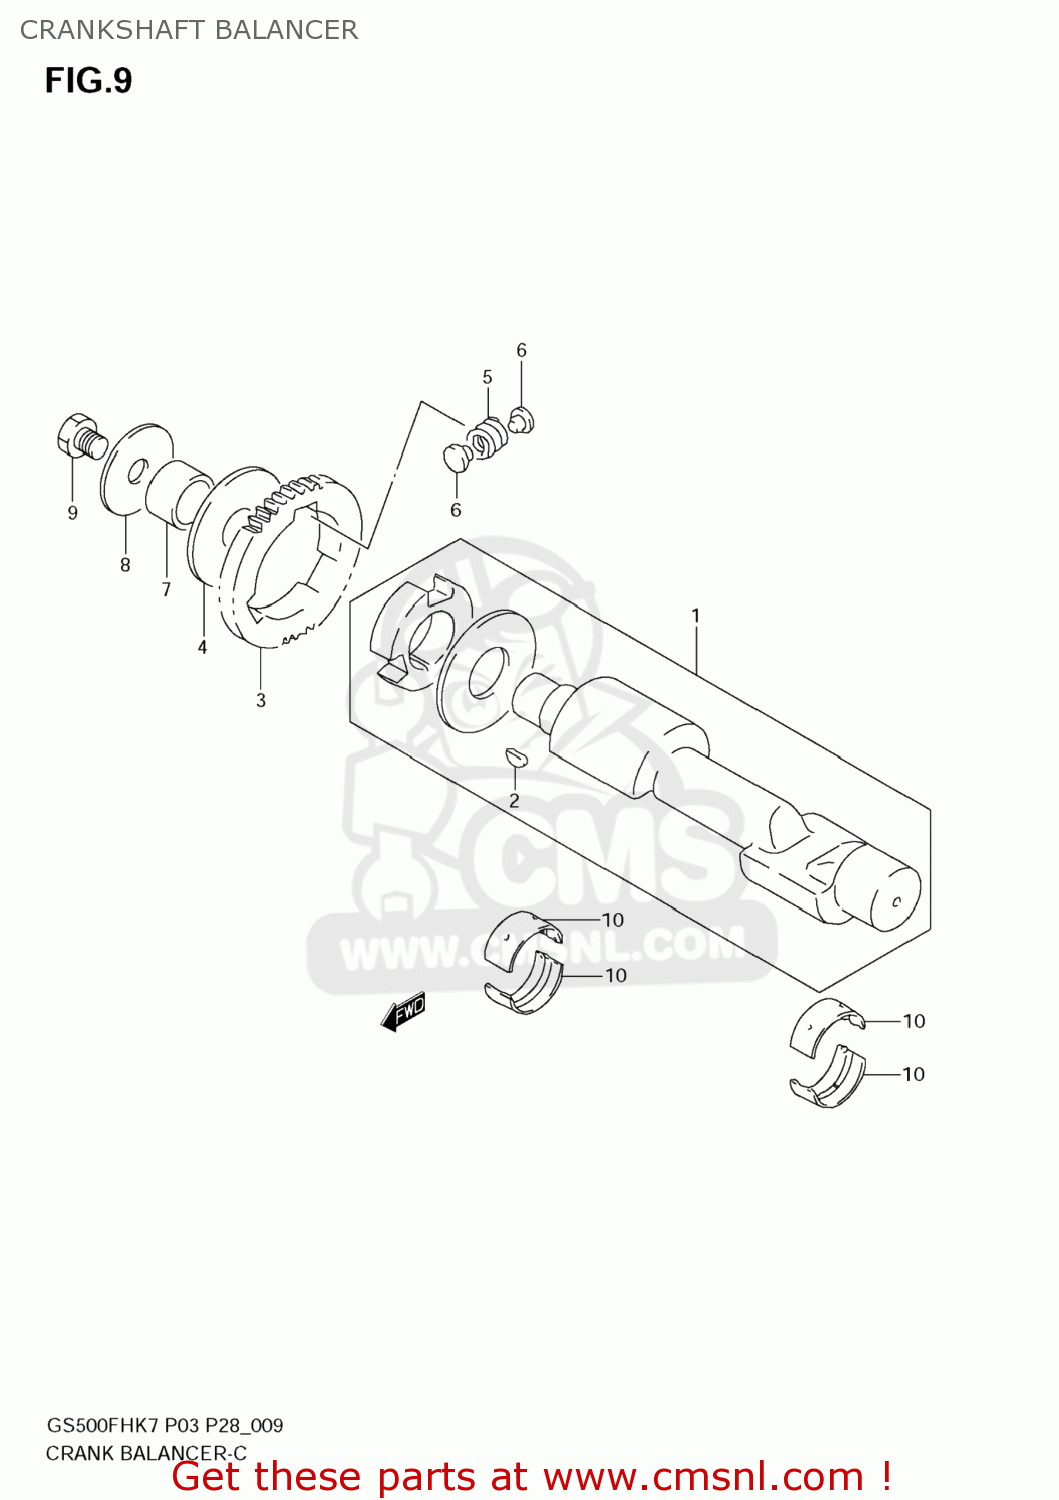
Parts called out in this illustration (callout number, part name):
1	BALANCER,CRANK
2	KEY
3	RACE,CRK BAL DRIVEN GEAR INNER
4	WASHER(24X70X3)
5	SPRING
6	PIN
7	SPACER(24X30.5X12.5)
8	WASHER(12X50X3)
9	BOLT
10	BEARING,CRANKSHAFT(GREEN)
